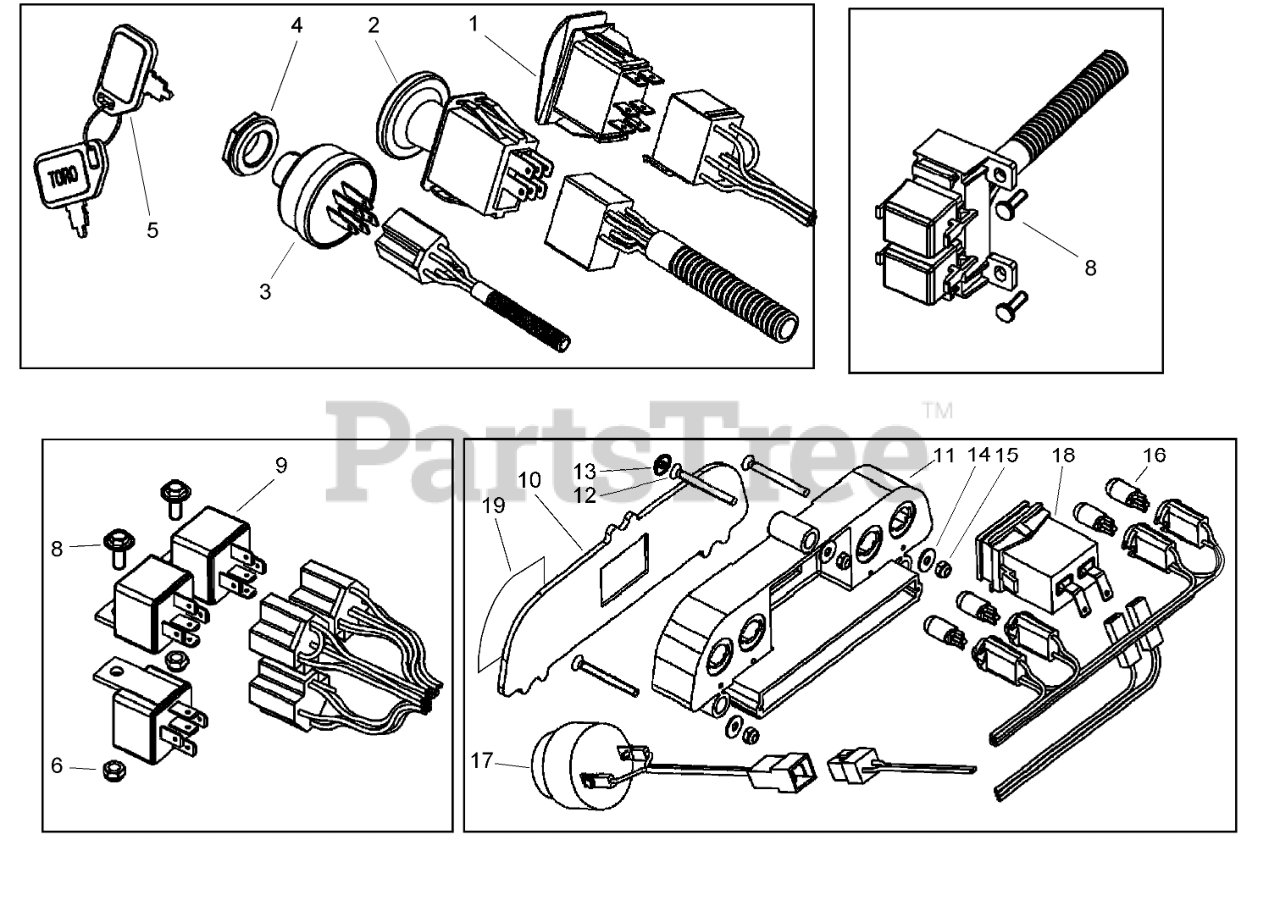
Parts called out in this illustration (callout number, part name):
1	SWITCH-CRUISE
2	SWITCH-PTO
3	SWITCH-IGNITION
4	NUT-HEX
5	KEY-IGNITION
6	NUT-LOCK
8	SCREW-HEX
10	LENS-DASH
11	HOUSING-LIGHT, INDICATOR
13	CAP-SCREW
14	WASHER
15	NUT-HEX
17	BUZZER
18	HOURMETER
19	DECAL-DASH
